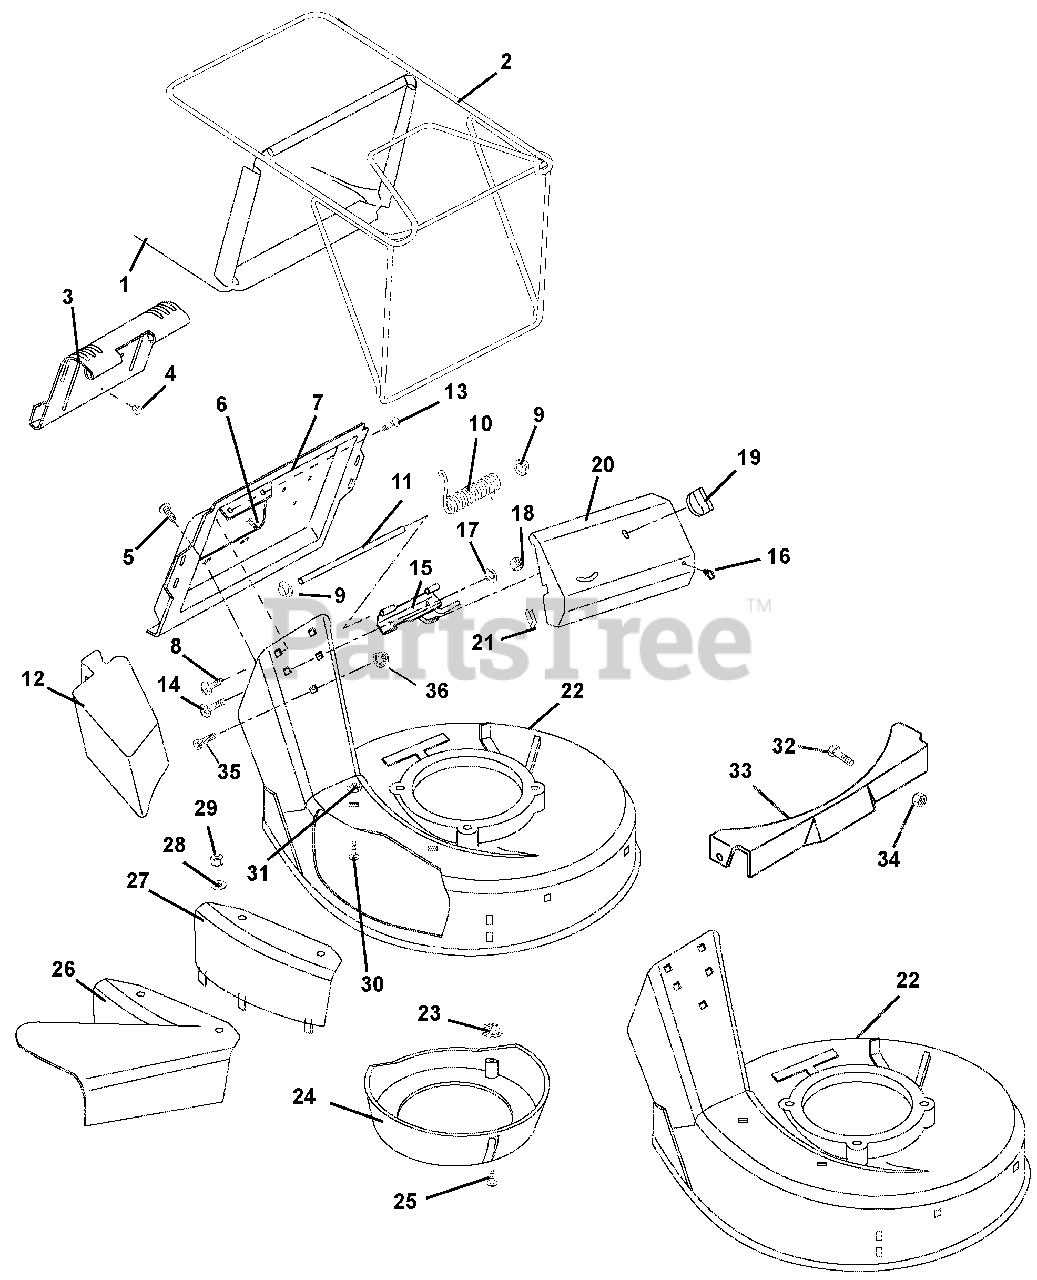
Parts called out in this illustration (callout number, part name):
1	Bag, Consumer Black
2	Frame, Bagger
3	Door, Catcher Plate
4	Button Bumper
5	Screw, Tapping Hex Washer 12-24 x .50
6	Screw, Tapping 10-24 x .38 Pan Head
7	Plate, Catcher
8	Bolt, Round Head Square Neck .25-20 x .38
9	Nut, Push
10	Spring, Torsion .120 x .68 x 3.09
11	Pin, Door
12	Mulch Master Mulcher Accessory
13	Nut, Locking Flange .25-20
14	Bolt, Round Head Square Neck .25-20 x .75 Grade 5
15	Hinge Base Weldment
16	Clip, Snap In (911137, 264, 265)
17	Washer, Locking .25 x .077
18	Nut, Hex .25-20
19	Nut, Wing (911136, 137, 262, 263, 264, 265)
20	Drive Cover (911136, 137, 262, 263, 264, 265)
21	Trim Bumper
22	Mower Pan Head with Decals (911136, 137, 262, 263, 264, 265)
22	Mower Pan Head with Decals (911260, 261)
23	Grommet, Plastic
24	Baffle, Center
25	Screw, Tapping 10-16 x .62 Hex Washer Head
26	Side Discharge Assembly
27	Side Discharge Cover
28	Washer, Flat Steel .406 x .812 x .065
29	Nut, Locking Nylon .312-18
30	Bolt, Round Head Square Neck .31-18 x .75 Grade 2
31	Nut, Push .312
32	Bolt, Round Head Square Neck .31-18 x .50 Grade 5 (911136, 137, 262, 263, 264, 265)
33	Front Panel (911136, 137, 262, 263, 264, 265)
34	Nut, Locking-Top-Flange .31-18 (911135, 136, 137, 138)
35	Bolt, Hex .38-16 x .50 Grade 5 (911260, 261)
36	Nut, Locking Flange Nut, .375-16 (911260, 261)
